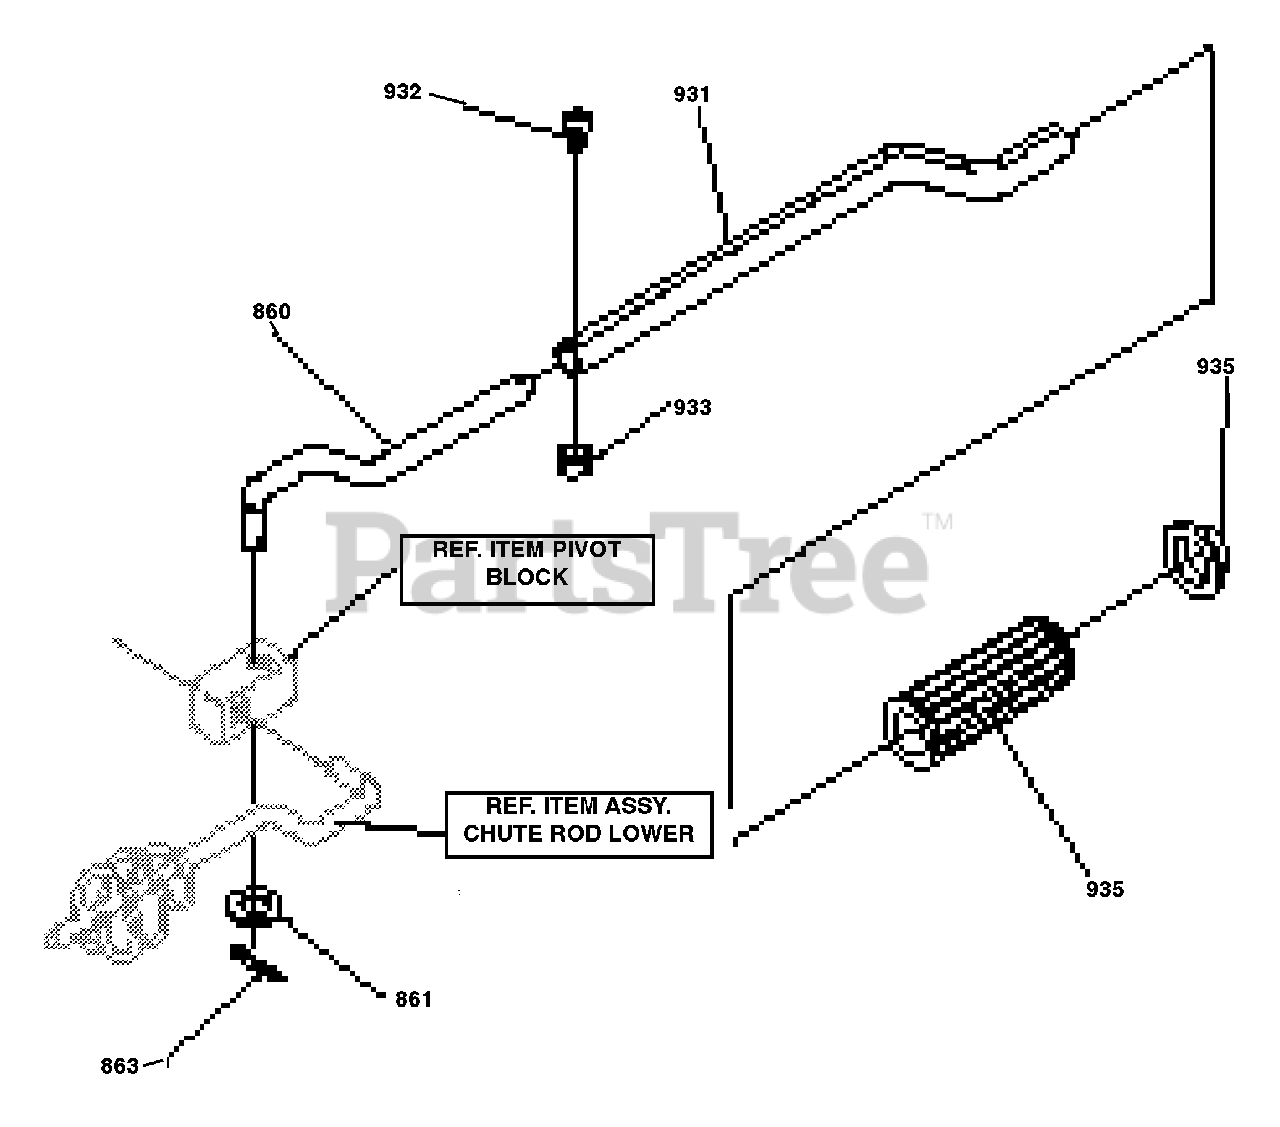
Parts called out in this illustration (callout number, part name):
860	ROD, MID CHUTE CTL
861	WASHER, FLAT .40 X .75 X .025
863	PIN, COTTER .090 DIA X .75 LG
931	ROD CHUTE CTRL UPR, ASSY
932	SCREW, 10-32 X .88 SLTRHD
933	NUT, #10-32 CTRLK
934	KNOB, CHUTE CRANK
